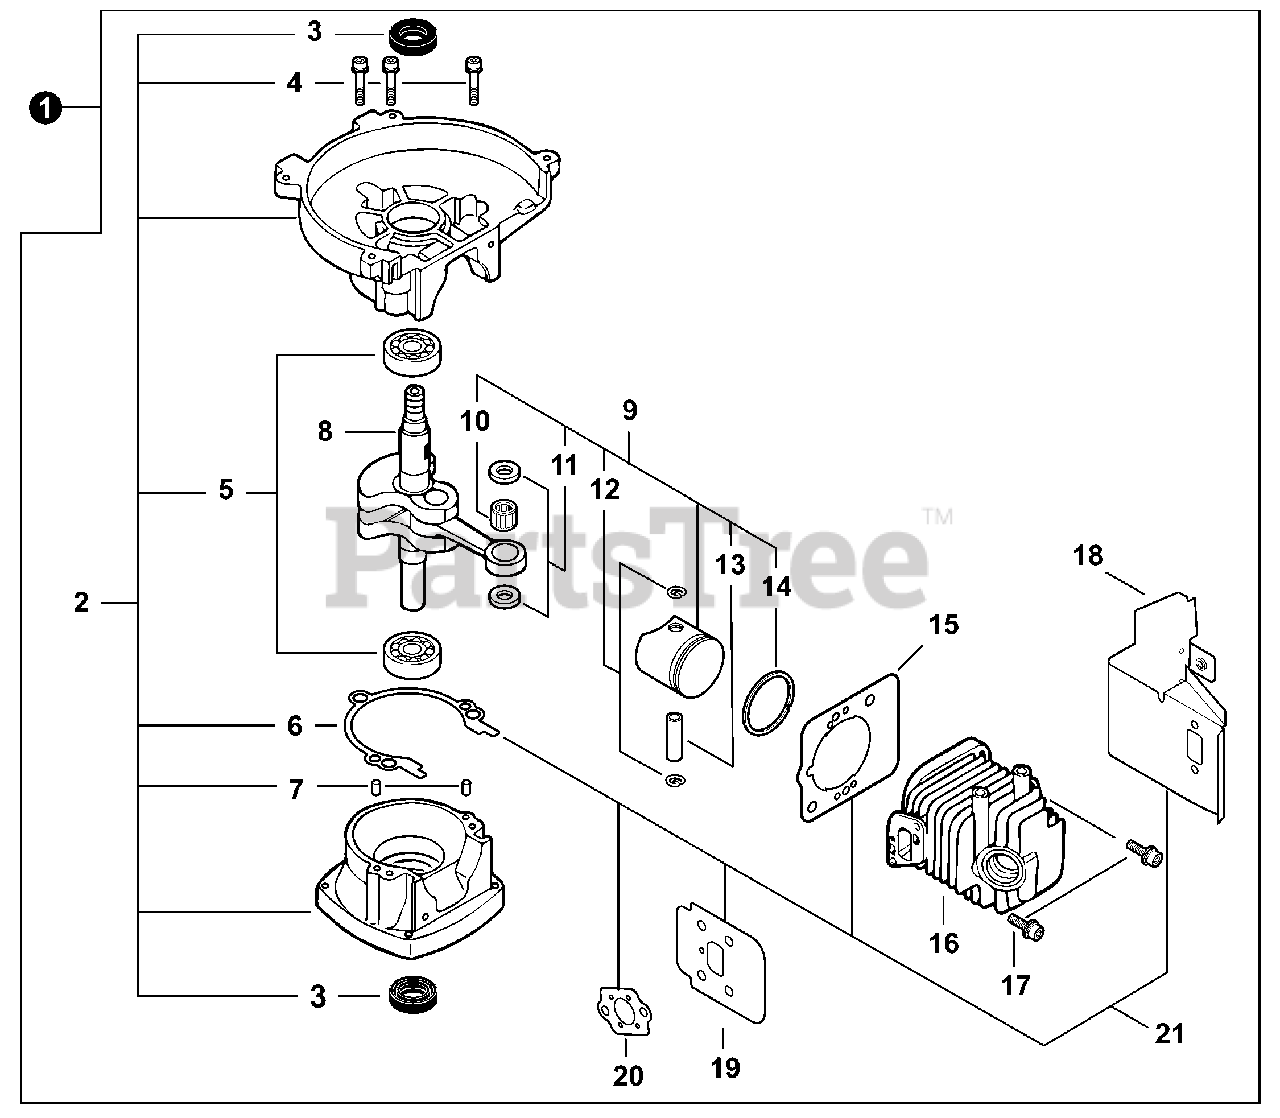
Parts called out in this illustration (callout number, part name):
1	SHORT BLOCK
2	CRANKCASE KIT
3	SEAL, OIL 12
4	BOLT 5×28
5	BEARING, BALL 6201
6	GASKET, CRANKCASE
7	PIN, LOCATING 4×8
8	BEARING, NEEDLE 8
9	PISTON KIT
10	CRANKSHAFT ASSY
11	WASHER, THRUST 8.2×13×0.5
12	RING, SNAP
13	PIN, PISTON 5×8×25.5
14	RING, PISTON
15	GASKET, CYLINDER
16	CYLINDER
17	BOLT 5×22
18	HEAT SHIELD, EXHAUST
19	HEAT SHIELD, INTAKE
20	GASKET, INTAKE
21	GASKET KIT
